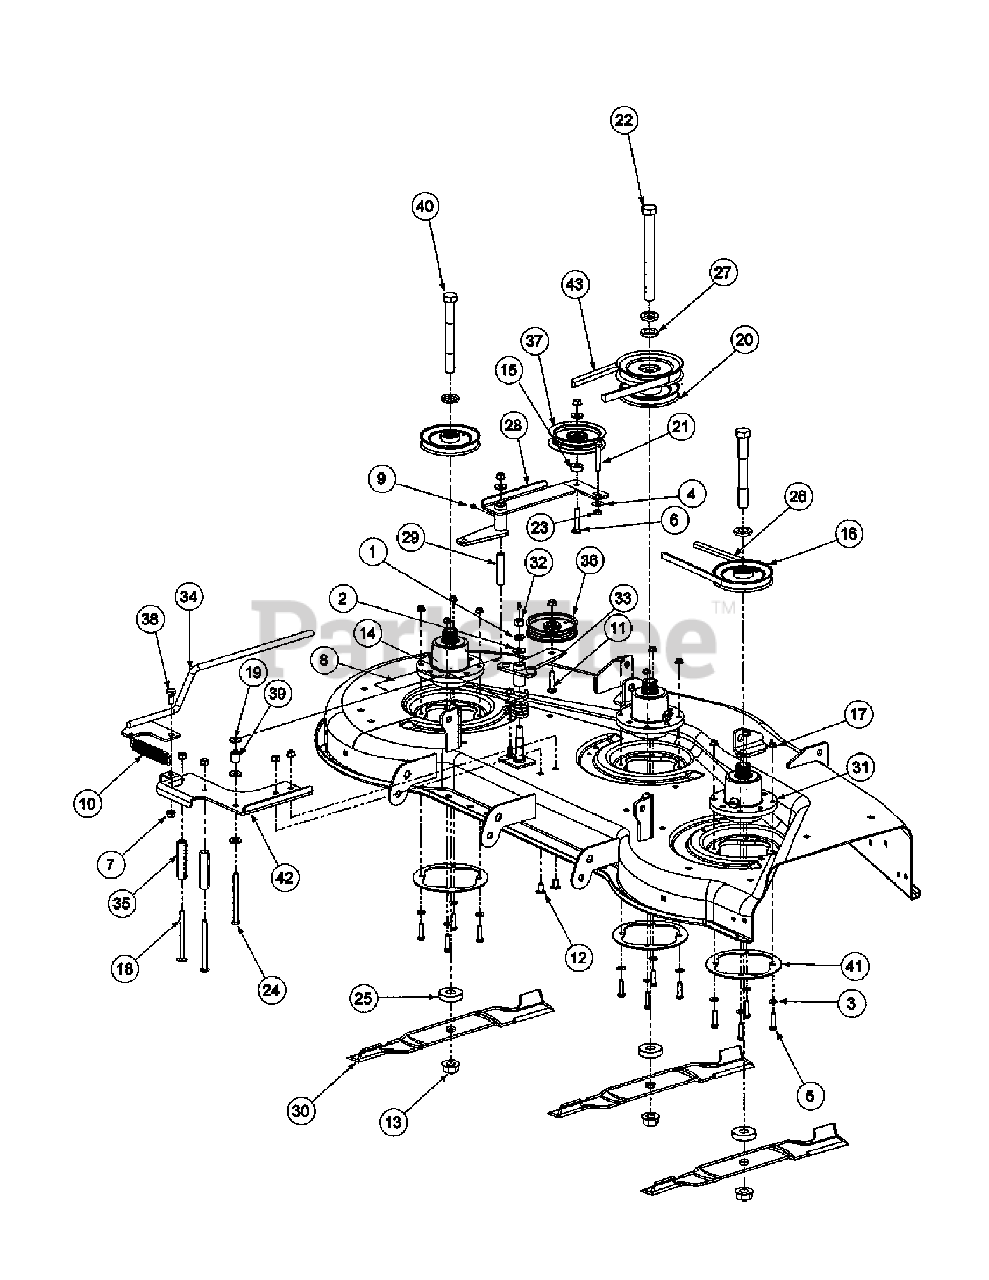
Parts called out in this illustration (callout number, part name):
1	Washer, Lock, 1/2"
2	Washer, Flat, SAE, 1/2
3	Washer, Flat, 5/16
4	Lock Washer, SAE, 3/8
5	Hex, Cap, Screw, 5/16-18, 1-1/4
6	Carriage, Bolt, 3/8-16 x 2
7	Nut, Hex, Flange Lock, 3/8-16
8	Decal, Rotating Blade
9	Fitting, Grease, 1/4-28 x 3/16
10	Spring, Extension, 1.0 OD x 5.125"
11	Bolt, Carriage, 3/8-16 x 1.75
12	Bolt, Carriage, 3/8-16 x .75"
13	Nut, Hex, Flange Lock, 3/4-16
14	Spring, Idler Torsion
15	Spacer, .406 ID x 1.00 OD x .3
16	Pulley-V, 4.65 P.D.
17	Hexflange, Lock, Nut, 5/16-18
18	Carriage, Bolt, 3/8-16 x 4.5
19	Washer, Flat, .411 x 1.25 x 1.00
20	Double, Pulley
21	Belt Retaining Stud, 3/8"
22	Screw, Hex, Cap. 3/4-16 x 8.00"
23	Nut, Jam, 3/8-16
24	Hex, Cap, Screw, 3/8-16, 4.50
25	Spacer, .76 ID x 2.00 OD x .477
26	Belt, Blade, 120" Long
27	Spacer, .812 ID x .218 Long
28	Arm, Idler, Deck Drive
28	Bearings
29	Spacer, .39 ID x .625 OD x 2.75
30	Blade, 20.5, High Lift
31	Spindle Assy, Aluminum, 60 Deck
32	Nut, Hex, 1/2-20
33	Arm Assy, Idler, Bearing 60
33	Bearings
34	Rod Assy, Mount, Idler Spring
35	Spacer, .505 x .75 x 3.31
36	Flat Pulley with Flanges
37	Pulley, Idler, Deck Take up
38	Bolt, Shoulder, .50 x .27 Long, 3/8-16
39	Spacer, .38510 x .750D x 1.063
40	Hex, Cap, Screw, 3/4-16, 6.50
41	Plate, Deck, Reinforcement
42	Bracket Assy, Mount, 60 Idler Arm
43	V-Belt PTO, B Section x 84.2 Long
